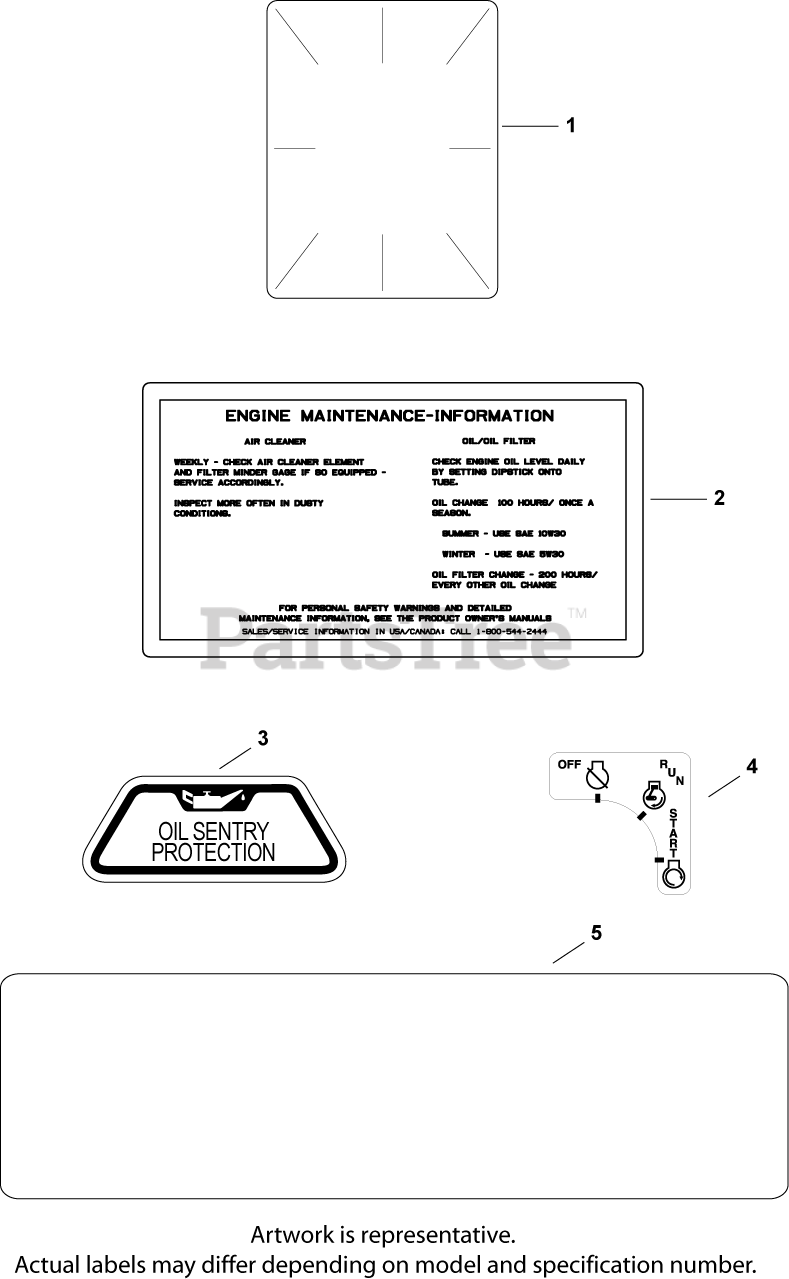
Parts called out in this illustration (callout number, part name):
1	DECAL, CLEAR LAMINATE USE 25 113 70-S
2	DECAL, AIR CLEANER - (#DSC)
3	DECAL, OIL SENTRY - (#DSC)
4	DECAL, KEY SWITCH
5	DECAL, 18 HP
